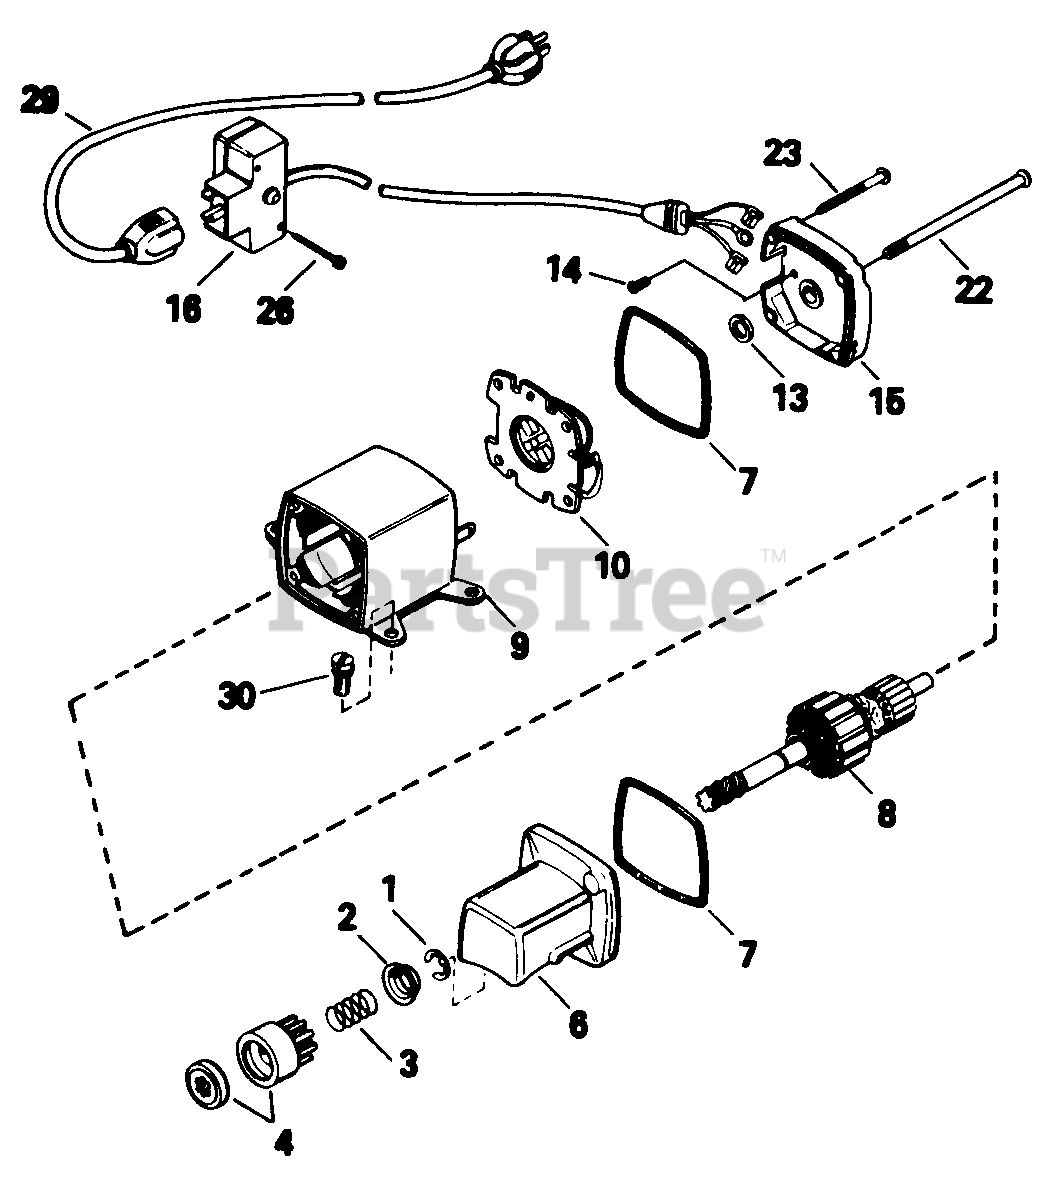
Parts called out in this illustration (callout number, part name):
1	Ring, Retainer
2	Retainer, Spring
3	Spring, Anti-Drift
4	Nut & Gear
6	Cap Ass'y., Drive End
8	Armature
9	Housing Ass'y.
10	Card Ass'y., Brush
13	Washer, Thrust
14	Screw, Ground
15	Cap Ass'y.,Commutator End
16	Box Ass'y., Switch
22	Bolt, Case
23	Screw, Grounding
26	Screw, Hex Hd. Self-Tap, 6-32 x 21/2
29	Cord, Extension (10'6")
30	Screw, Hex Hd. Self-Tap, 1/4-20 x11/16
